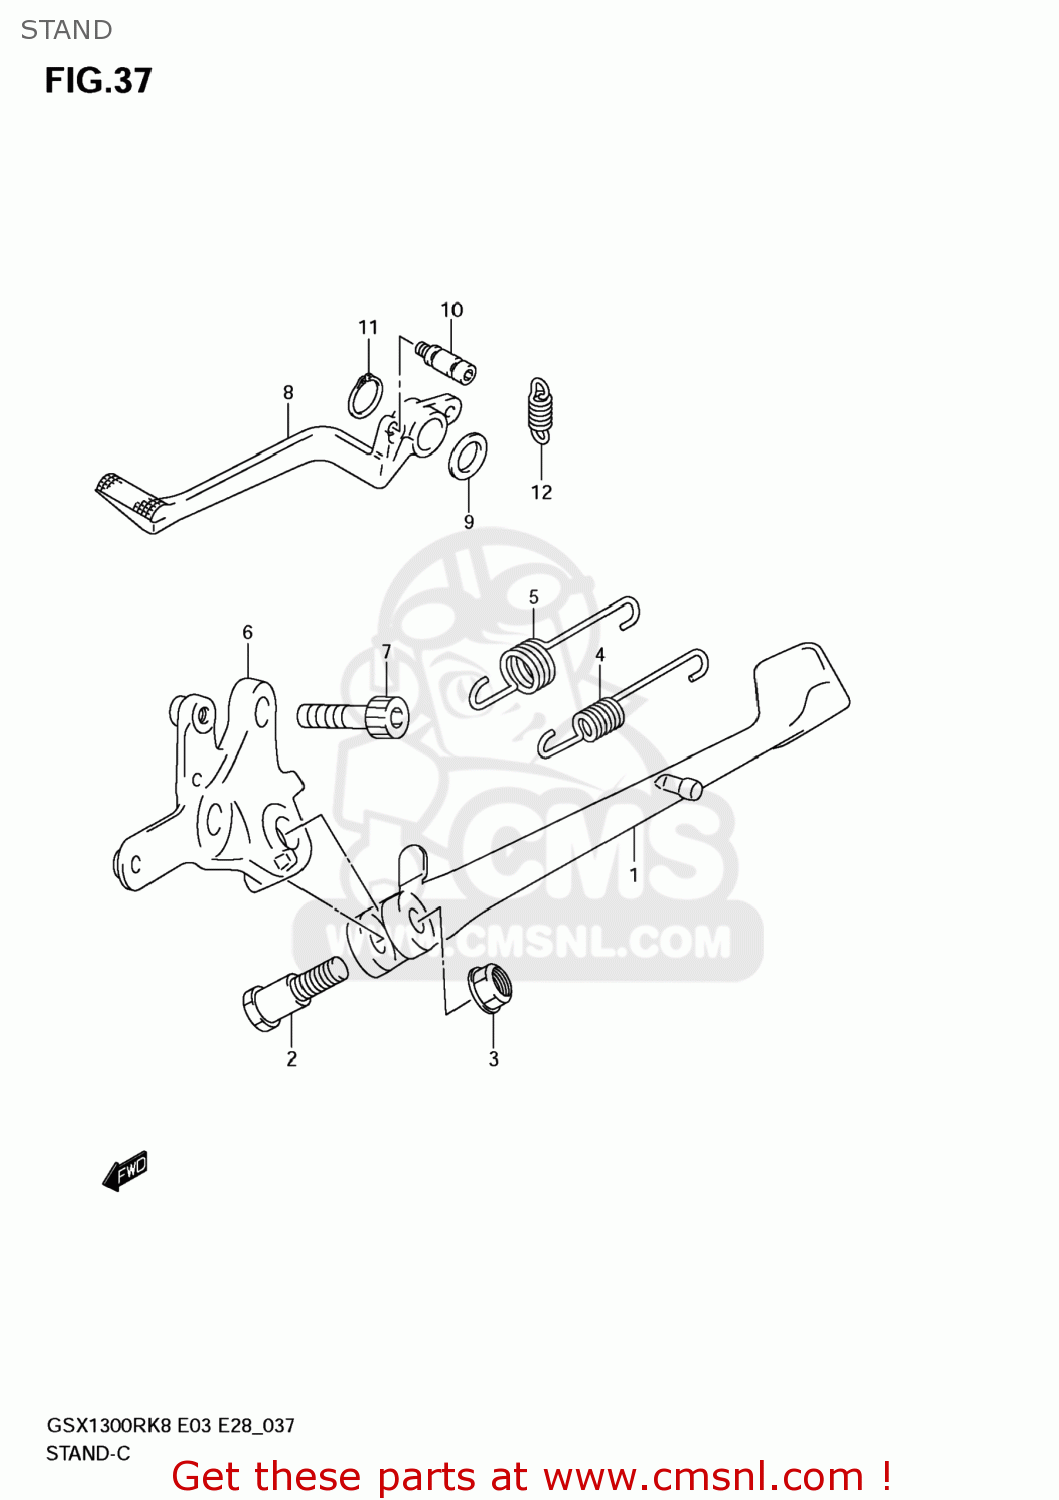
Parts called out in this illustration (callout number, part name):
1	STAND,PROP
2	BOLT(10X21)
3	NUT
4	SPRING
5	SPRING
6	BRACKET,PROP STAND
7	BOLT(12X35)
8	PEDAL,BRAKE
9	WASHER(18X24X1)
10	HOOK,RETURN SPRING
11	CIRCLIP
12	SPRING
